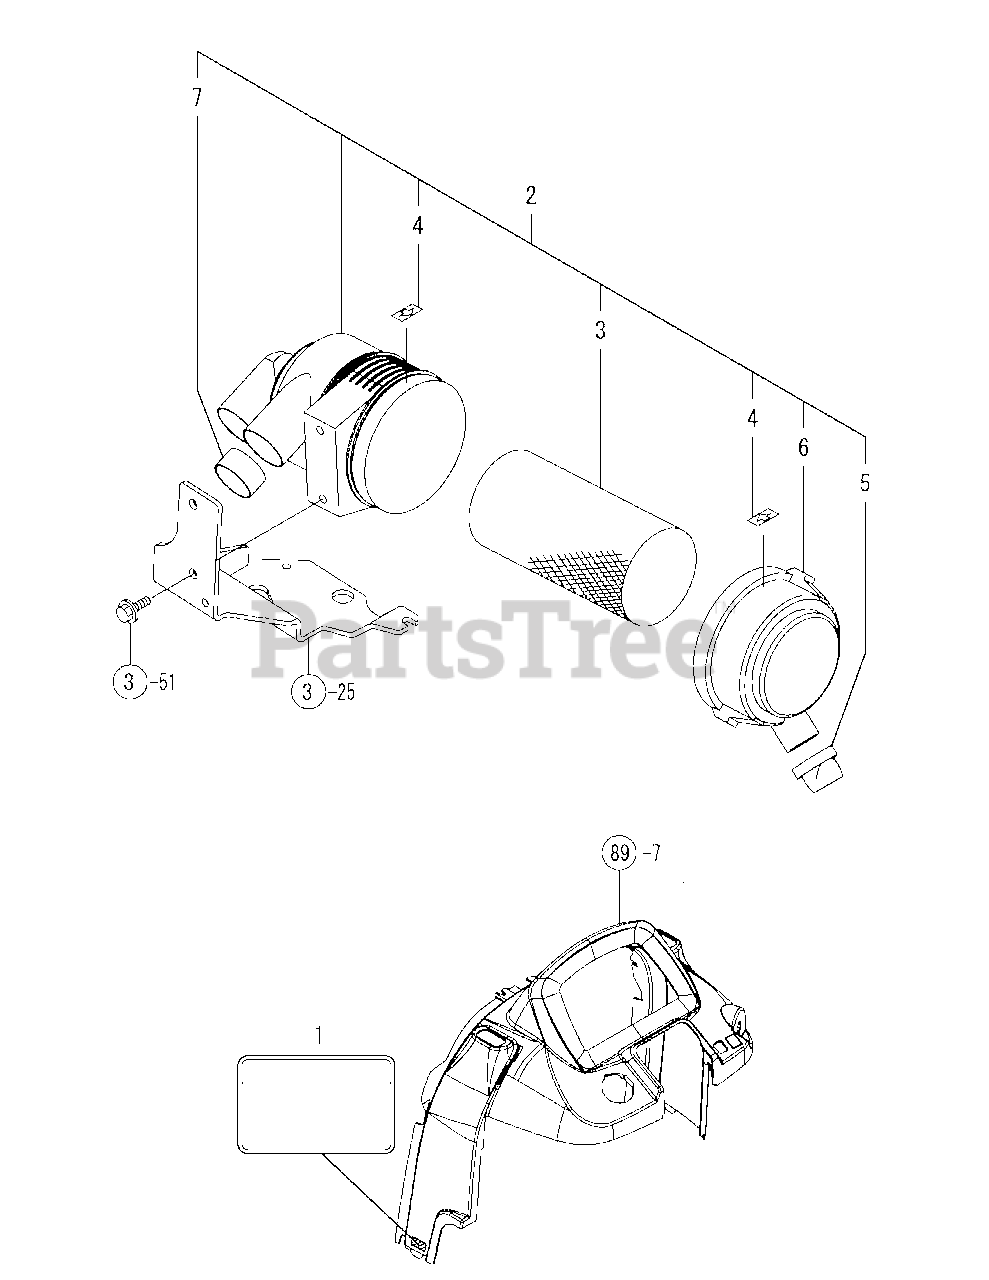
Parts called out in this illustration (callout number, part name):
1	LABEL, FUEL OIL
2	CLEANER ASSY, AIR
3	ELEMENT, AIR CLEANER
5	VALVE, UNLOADER
